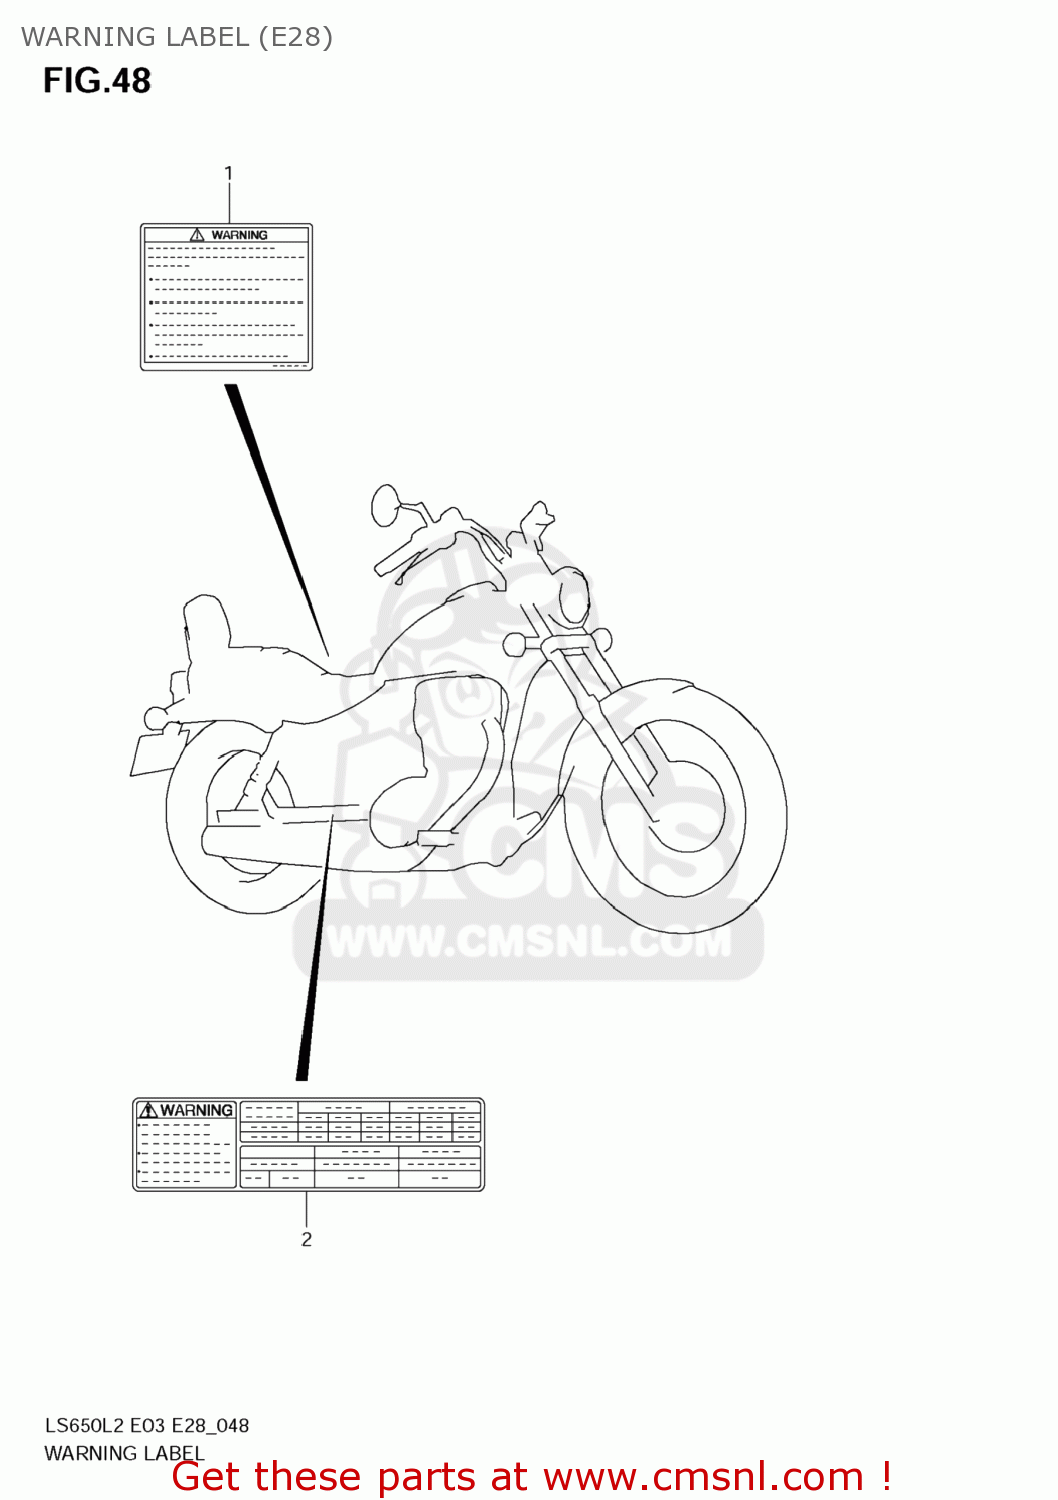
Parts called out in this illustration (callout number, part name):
1	LABEL,GENERAL WARNING
2	LABEL,TIRE INFORMATION
3	MANUAL,OWNER'S
